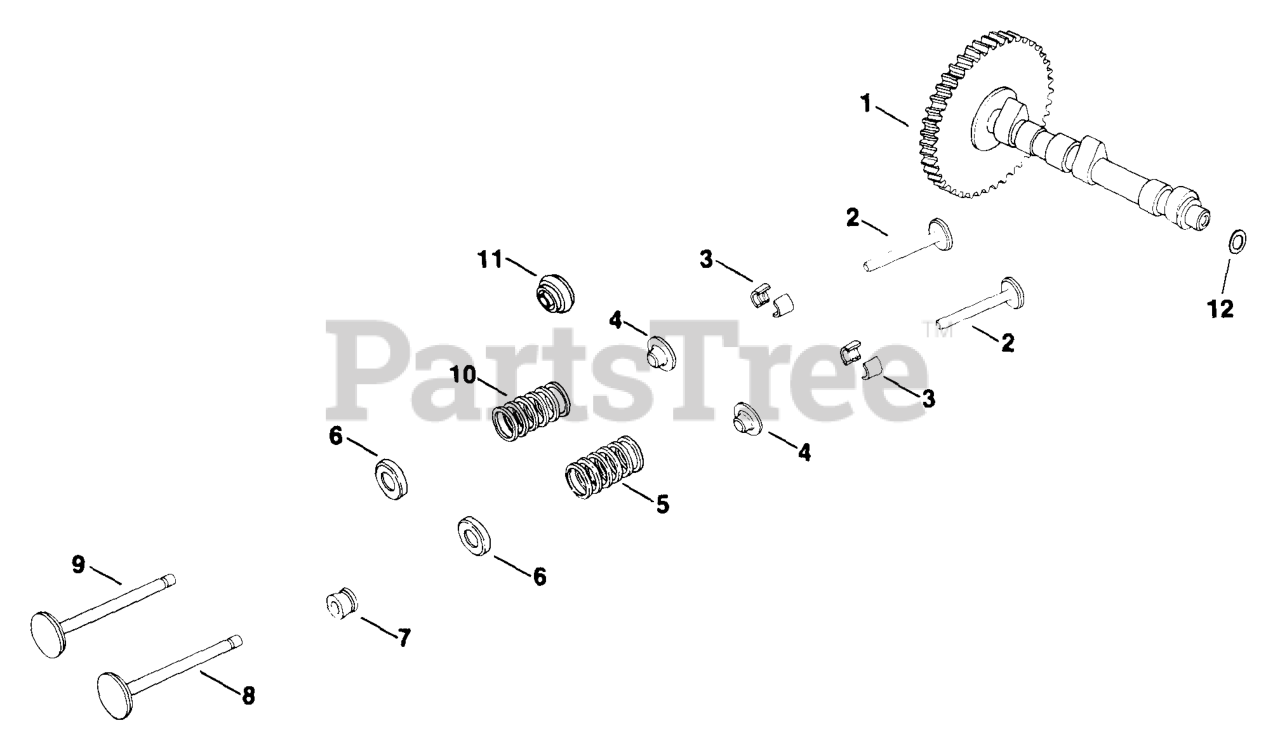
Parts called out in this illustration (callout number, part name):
2	TAPPET - (#DSC)
3	KIT, RETAINER
4	RETAINER, VALVE SPRING
5	SPRING - DISCONTINUED
6	RETAINER - USE 235011
7	SEAL - USE 52 032 13
8	VALVE - (#DSC)
9	VALVE - USE 52 016 02
10	SPRING - DISCONTINUED
12	SPACER - (#DSC)
